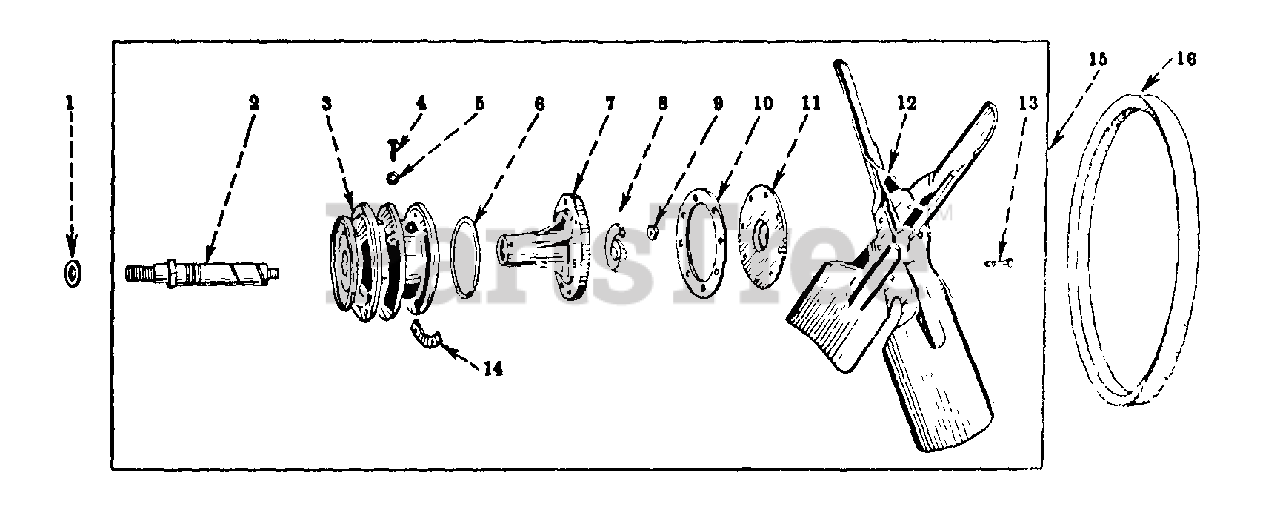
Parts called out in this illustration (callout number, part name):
1	WASHER, FAN SHAFT
2	SPINDLE AND BEARING ASSY
3	HUB ASSY
4	SCREW, OIL RETAINING
5	RING, 1/4 RECTANGULAR SEAL
6	GASKET, FAN HUB
9	NUT, 3/8-4 CDP P/T HEX
10	GASKET, FAN BEARING
11	CAP, FAN BEARING
13	SCREW, 10-32 X 9/16 SLT-FIL-HD MACH
14	NUT, DOUBLE
15	FAN AND HUB ASSY
